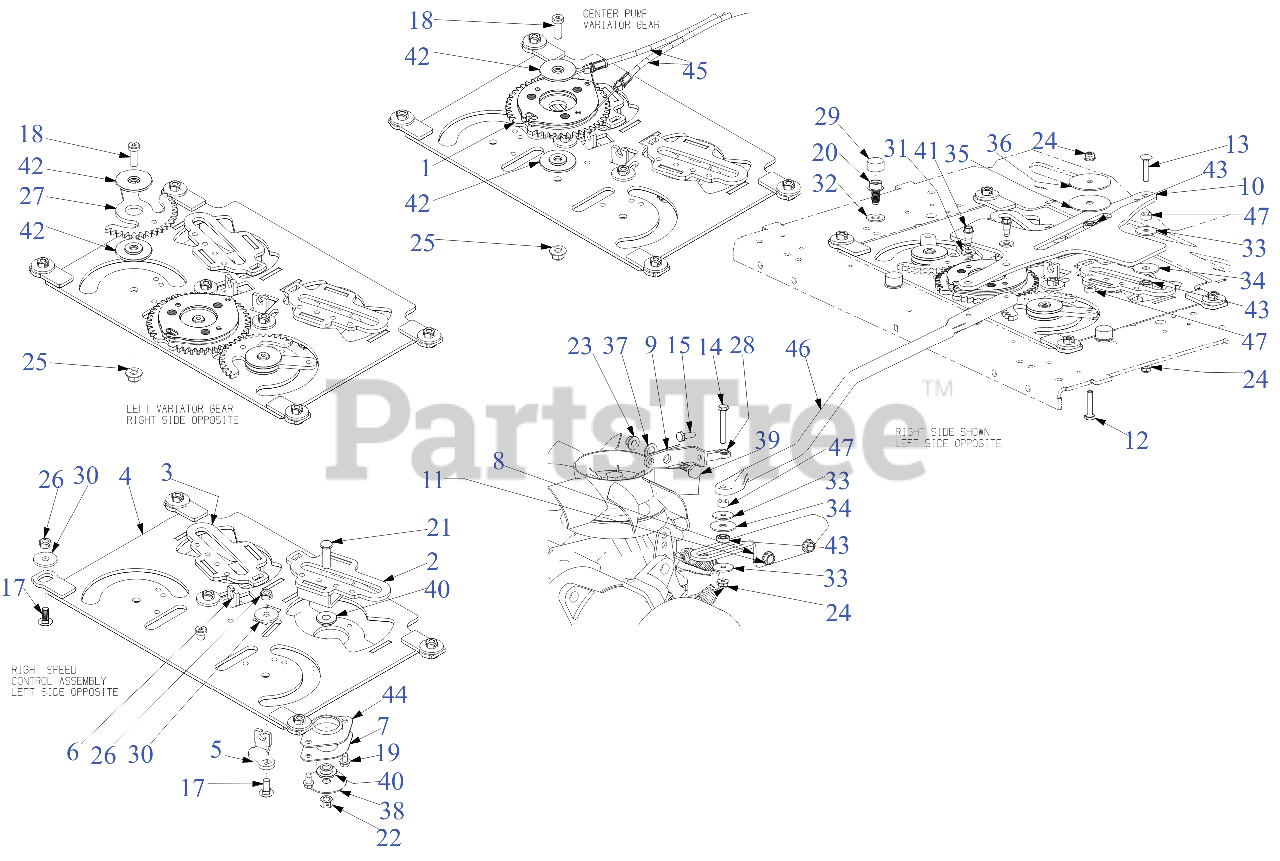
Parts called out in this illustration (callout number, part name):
2	PUMP CONTROL CAM ASSEMBLY (RH)
3	PUMP CONTROL CAM ASSEMBLY (LH)
9	PUMP CONTROL BRACKET
10	STEERING PUMP ACTUATOR ARM
11	SCREW 5/16-18 x .750
12	HEX SCREW 1/4-20 x 1.25
13	CARRIAGE BOLT 1/4-20 x 1.25 Gr5
14	HEX SCREW 1/4-20 x 1.75
15	HEX SCREW 1/4-28 x .75
17	CARRIAGE BOLT 5/16-18 x .75
18	SCREW 3/8-16 x 1
19	SCREW 1/4-20 X.500
20	SCREW 3/8-16 x 3/4
21	SCREW 3/8-16 x 1.25 GR5
23	FLANGE LOCK NUT 5/16-18
24	FLANGE LOCK NUT
26	HEX NUT LOCK CENTER
27	STEERING GEAR YOKE
28	END ROD (RH)
29	SLIDE CAP
30	FLAT WASHER
31	FLAT WASHER.344X.75X.1
32	FLAT WASHER.40 ID
33	FLAT WASHER
34	WASHER .355X1.25X.06THK
35	FLAT WASHER
36	FLAT WASHER
37	FLAT WASHER .469X.750X.054
38	HUB CAP WASHER .406 x 1.92 x .060
39	SHOULDER SCREW .437 DIA x .265
40	SHOULDER SPACER
41	SCREW 5/16-18 x .750
42	SHOULDER SPACER
43	BALL BEARING .25 x .625 SPCL
44	BALL BEARING
45	TRANSMISSION CONTROL LINK CABLE
46	CONTROL PUMP ROD
